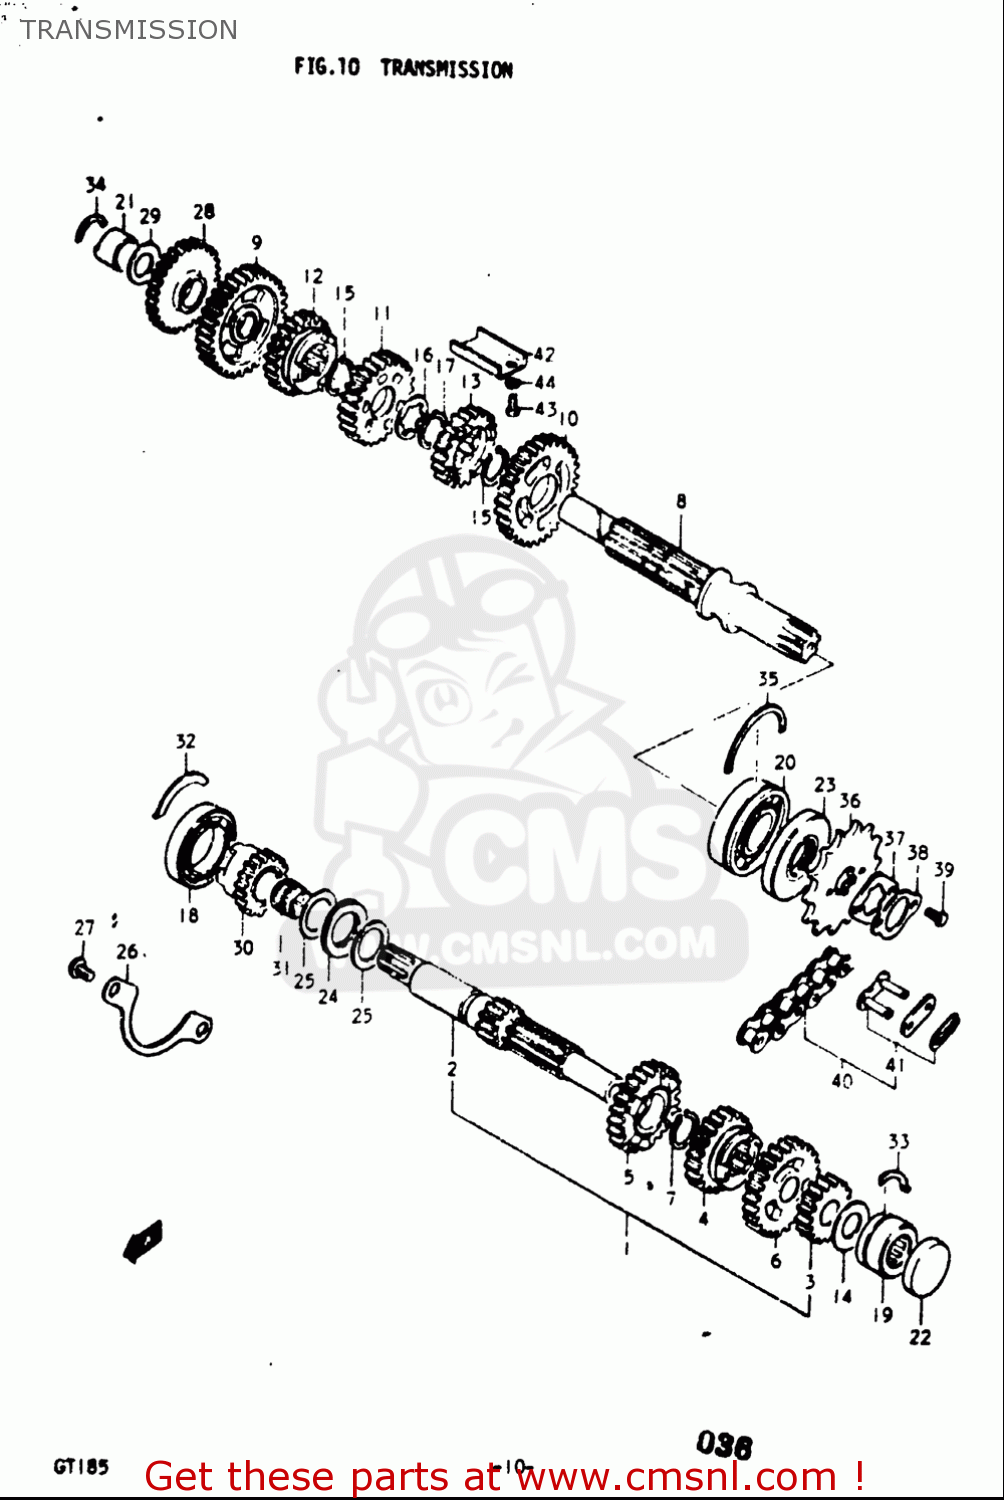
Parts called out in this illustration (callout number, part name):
3	GEAR,2ND DRIVE
4	GEAR,THIRD DRIVE
5	GEAR,4TH DRIVE
7	CIRCLIP
9	GEAR,1ST DRIVEN
10	GEAR,2ND DRIVEN
11	GEAR,3RD DRIVEN
12	GEAR,4TH DRIVEN
13	GEAR,5TH DRIVEN
14	WASHER
15	CIRCLIP
16	WASHER,LOCK
17	CIRCLIP
18	BEARING
20	BEARING(20X52X15)
22	PLUG
23	SEAL,OIL (20X52X7)
24	BEARING(21X32X2.85)
25	WASHER(21X30X0.8)
26	RETAINER,CNTR SHAFT BEARING
27	SCREW
29	WASHER
30	GEAR,KICK STARTER DRIVEN
31	BEARING(19.2X23.2X19)
33	KNOCK RING
36	SPROCKET,ENGINE
39	BOLT
40	CHAIN ASSEMBLY,DRIVE
41	JOINT,CHAIN
43	SCREW
44	WASHER,LOCK
